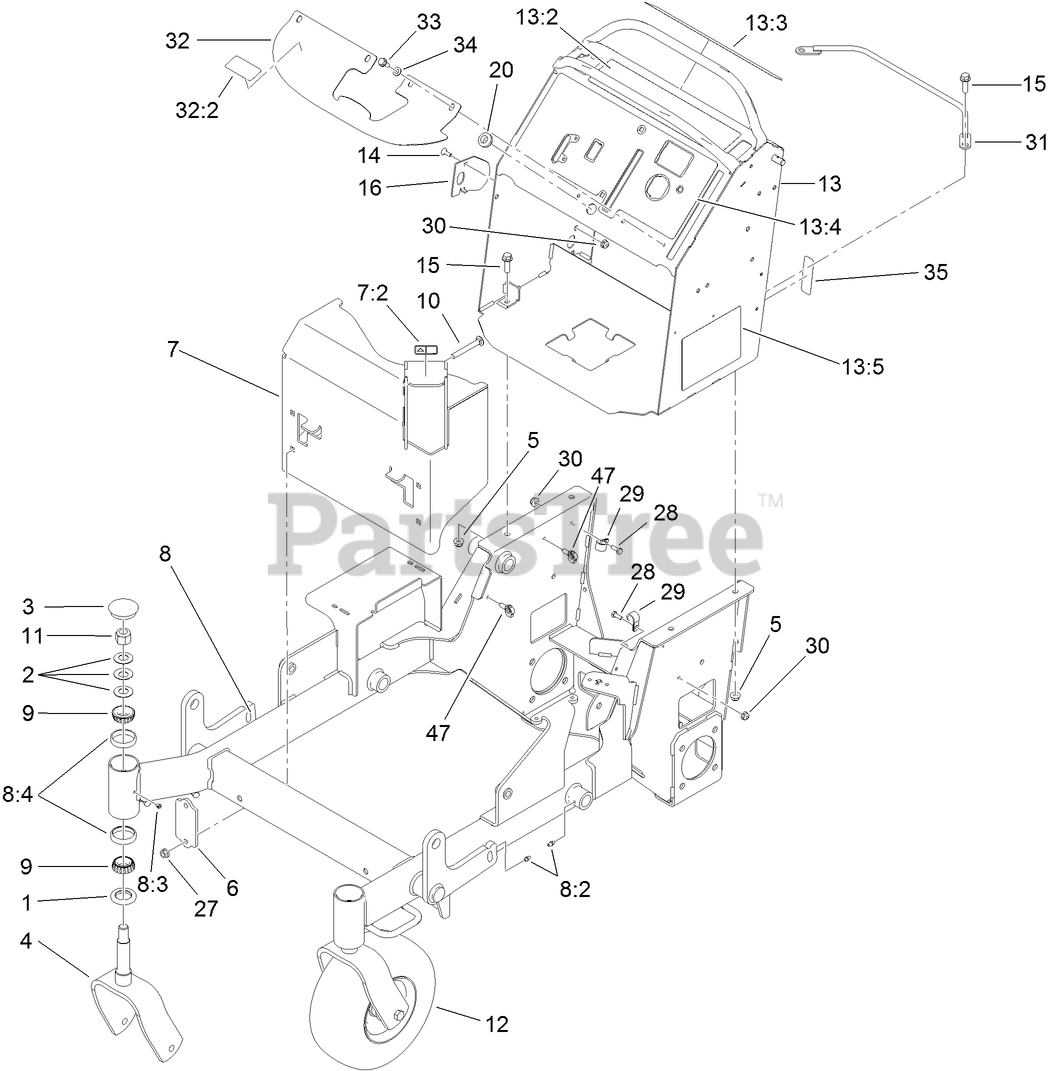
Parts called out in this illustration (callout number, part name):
1	SEAL-GREASE
2	WASHER-BELLVILLE
3	CAP-GREASE
4	FORK-CASTER
5	NUT-HF, NI
6	BRACKET-MOUNTING, GUARD
7	MUFFLER GUARD ASM
7:2	DECAL-WARNING
8	FRAME ASM
8:2	FITTING-GREASE
8:4	CUP-BEARING
9	BEARING-ROLLER, TAPERED
10	SCREW-CARR
11	NUT-LOCK, NI
12	WHEEL/TIRE AND BEARING ASM
13	CONTROL TOWER ASM
13:2	DECAL-OPC
13:3	DECAL-WARNING
13:4	DECAL-PANEL, CONTROL
13:5	DECAL-SERVICE/SPARK ARREST
14	BOLT-CARR
15	SCREW-HHF
16	PLATE-STRIKER
20	GROMMET
27	NUT-HF
28	SCREW-HH
29	CLAMP-CABLE
30	NUT-HF
31	RETAINER-CABLE
32	COVER-TANK
32:2	DECAL-FILL, FUEL
33	SCREW-HWHTF
34	WASHER-FLAT
35	DECAL-FUSE
47	CLIP-HARNESS
